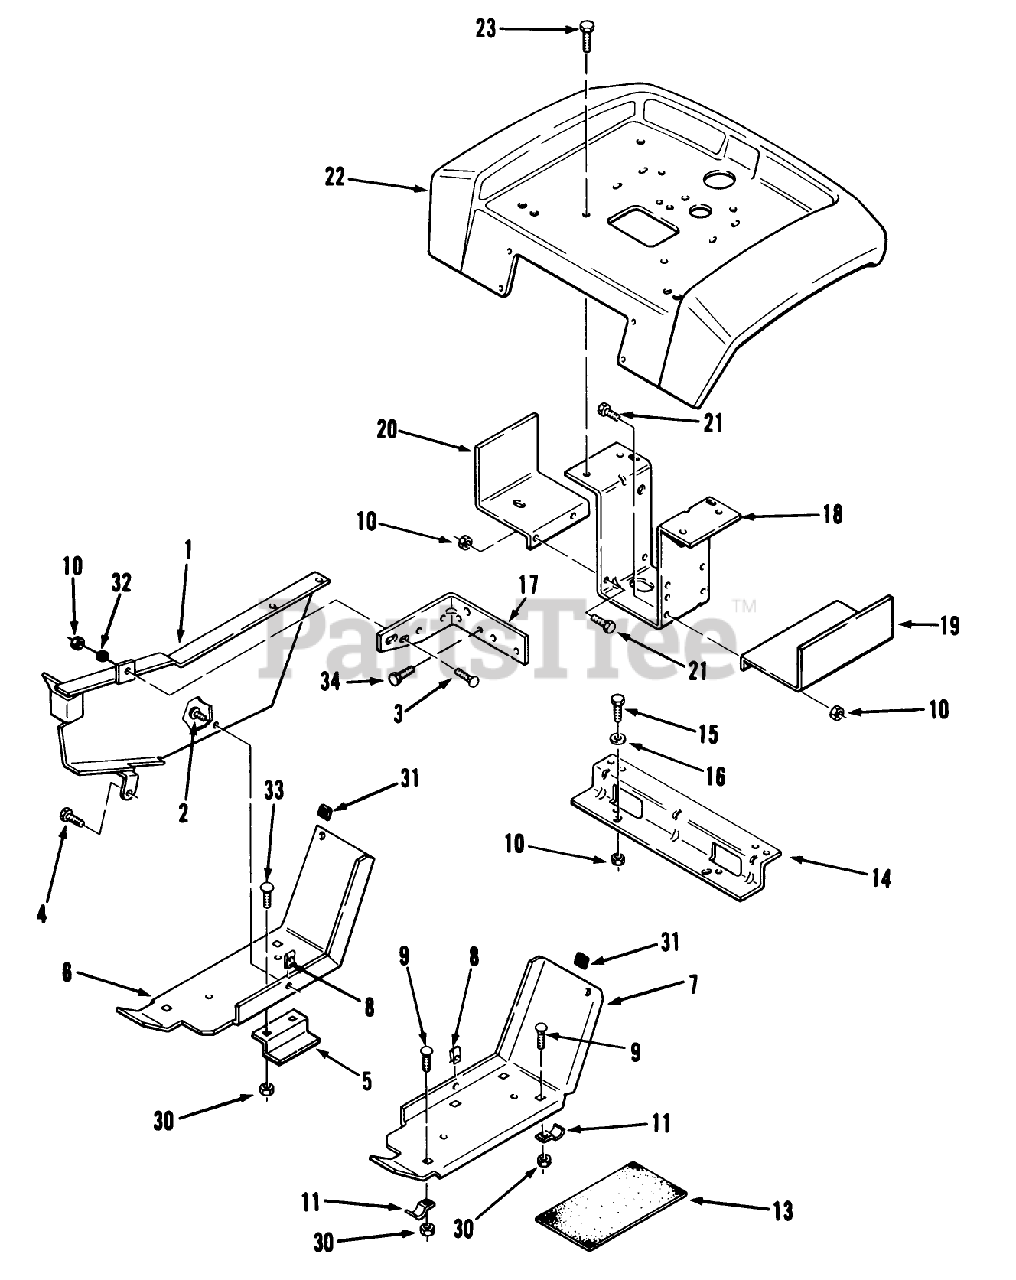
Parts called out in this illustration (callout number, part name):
3	BOLT-CARR
4	SCREW
7	FOOTREST LH *R
9	BOLT-CARR
11	BRACKET
13	Footrest Pad
16	WASHER 5/16 SAE
17	BRACKET-BELT*B
23	SCREW
31	BUMPER
